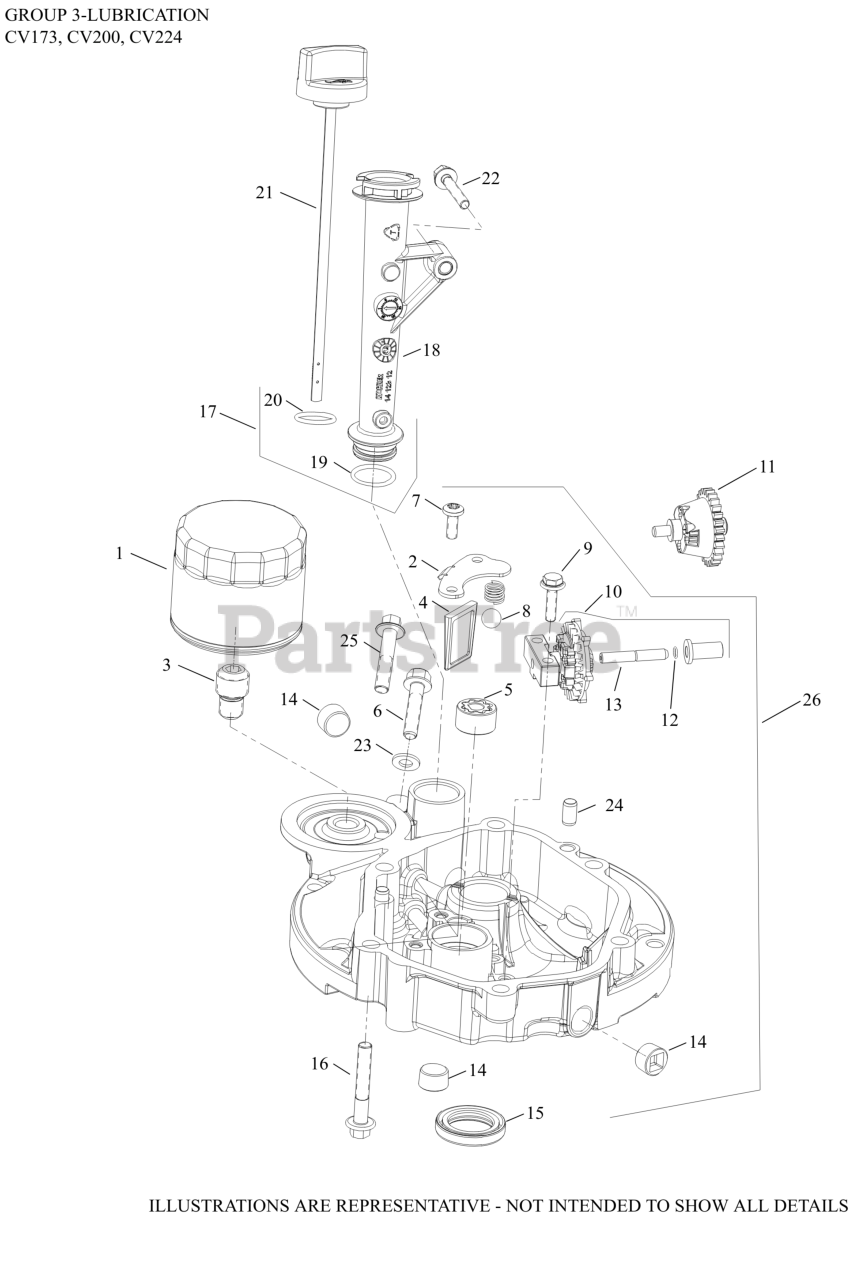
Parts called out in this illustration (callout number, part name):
1	FILTER, OIL
2	COVER, OIL PUMP SCREEN
3	NIPPLE, OIL FILTER
4	SCREEN, OIL
5	PUMP ASSEMBLY, OIL (GE-ROTOR)
7	SCREW, M6 X 16
8	BALL, STEEL COMPOSITE
9	SCREW, M6 X 22
10	GOVERNOR GEAR, ASSEMBLY
12	CLIP, GOVERNOR GEAR-DISCONTINUED
13	SHAFT, GOVERNOR GEAR-DISCONTINUED
14	PLUG, PIPE (W/SEALANT)
16	SCREW, HEX FLANGE (M8)-USE 25 086 456-S
17	KIT, DIPSTICK AND TUBE-(#1412320S)
18	TUBE ASSEMBLY, OIL FILL
19	O-RING, OIL FILL TUBE
20	O-RING (CAP)
21	CAP, DIPSTICK ASSEMBLY
22	SCREW, HEX FLANGE (M6)-(#25086435S)
23	WASHER, CLEAN OIL SCREW
24	PIN, DOWEL (8mm)
25	SCREW, CLOSURE PLATE
26	PAN, OIL ASSEMBLY (KIT)
